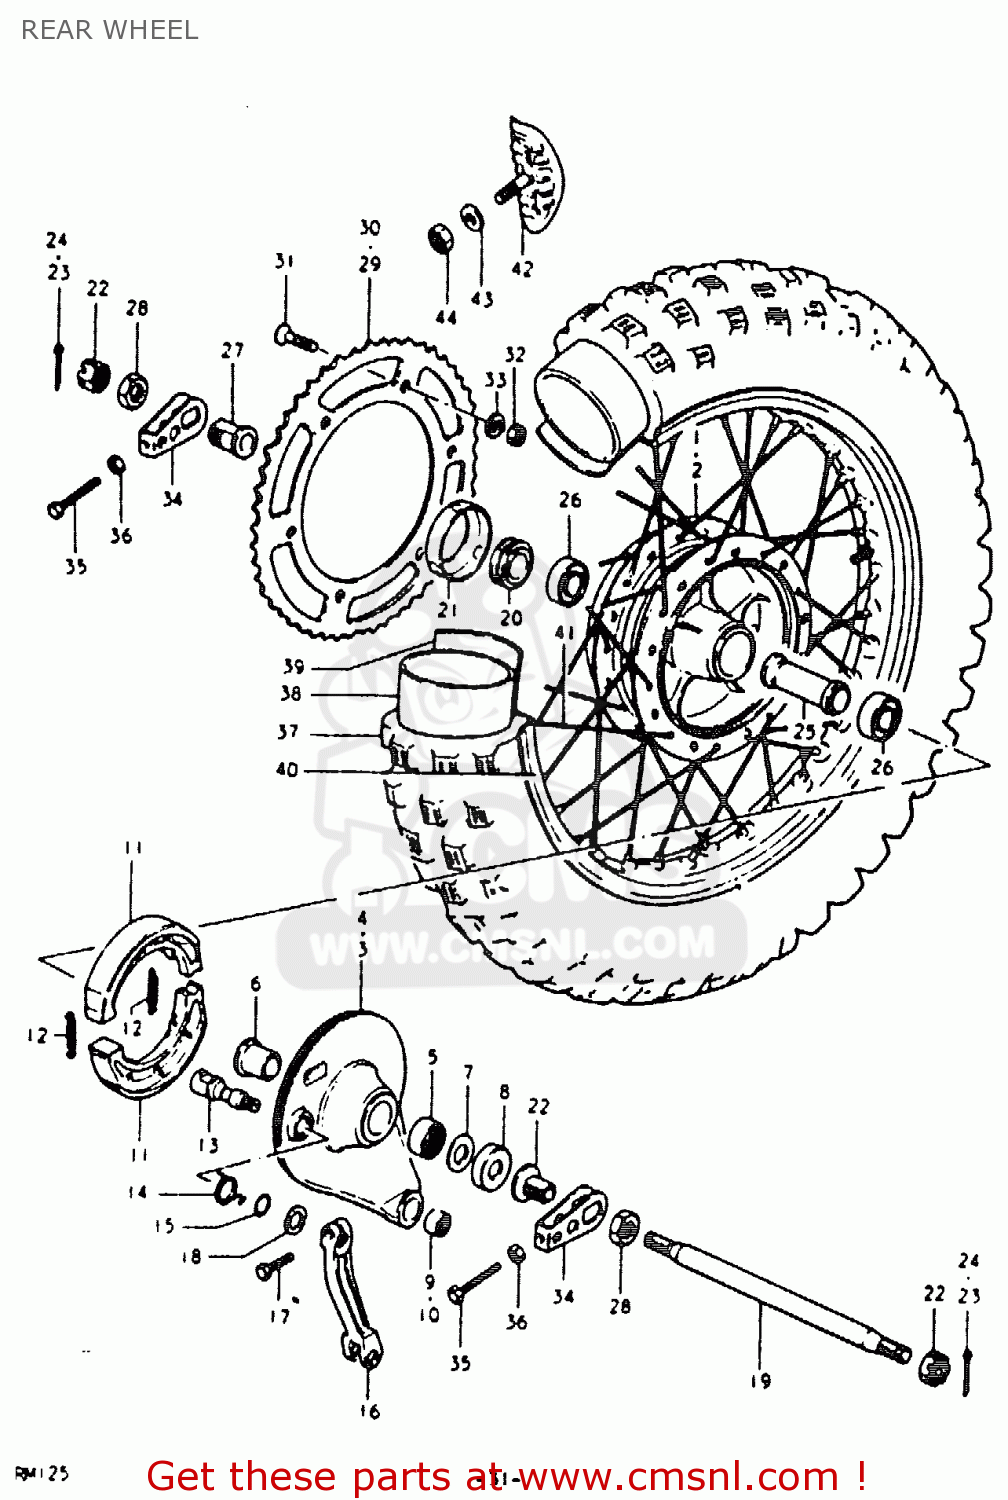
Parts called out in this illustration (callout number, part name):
2	HUB,REAR
4	PANEL SET,REAR HUB
5	BEARING(22X29X25)
6	SPACER,REAR HUB PANEL
7	WASHER
8	COVER, PANEL DUST SEAL
10	SPHERICAL BEARING,TORQUE
11	SHOE,BRAKE
12	SPRING(L:34)
13	CAM,FR BRAKE
14	SPRING
15	O RING(D:2.5,ID:11.4)
16	LEVER,RR BRAKE CAM
17	BOLT
18	WASHER(12.5X20X1)
19	AXLE,REAR
20	SPACER,REAR AXLE,RIGHT
21	HOLDER,REAR AXLE SPACER
22	NUT
24	COTTER PIN
25	SPACER,REAR HUB BEARING
26	BEARING
27	SPACER,CHAIN ADJUSTER
28	NUT
30	SPROCKET,REAR
31	SCREW(8X33.5)
32	NUT
33	WASHER
34	ADJUSTER,CHAIN
35	BOLT
36	NUT
37	TIRE
38	TUBE ASSEMBLY,WHEEL,INNER
39	PROTECTOR,INNER TUBE
40	RIM,REAR WHEEL
41	SPOKE SET,REAR
42	STOPPER,BEAD
43	WASHER
44	NUT
